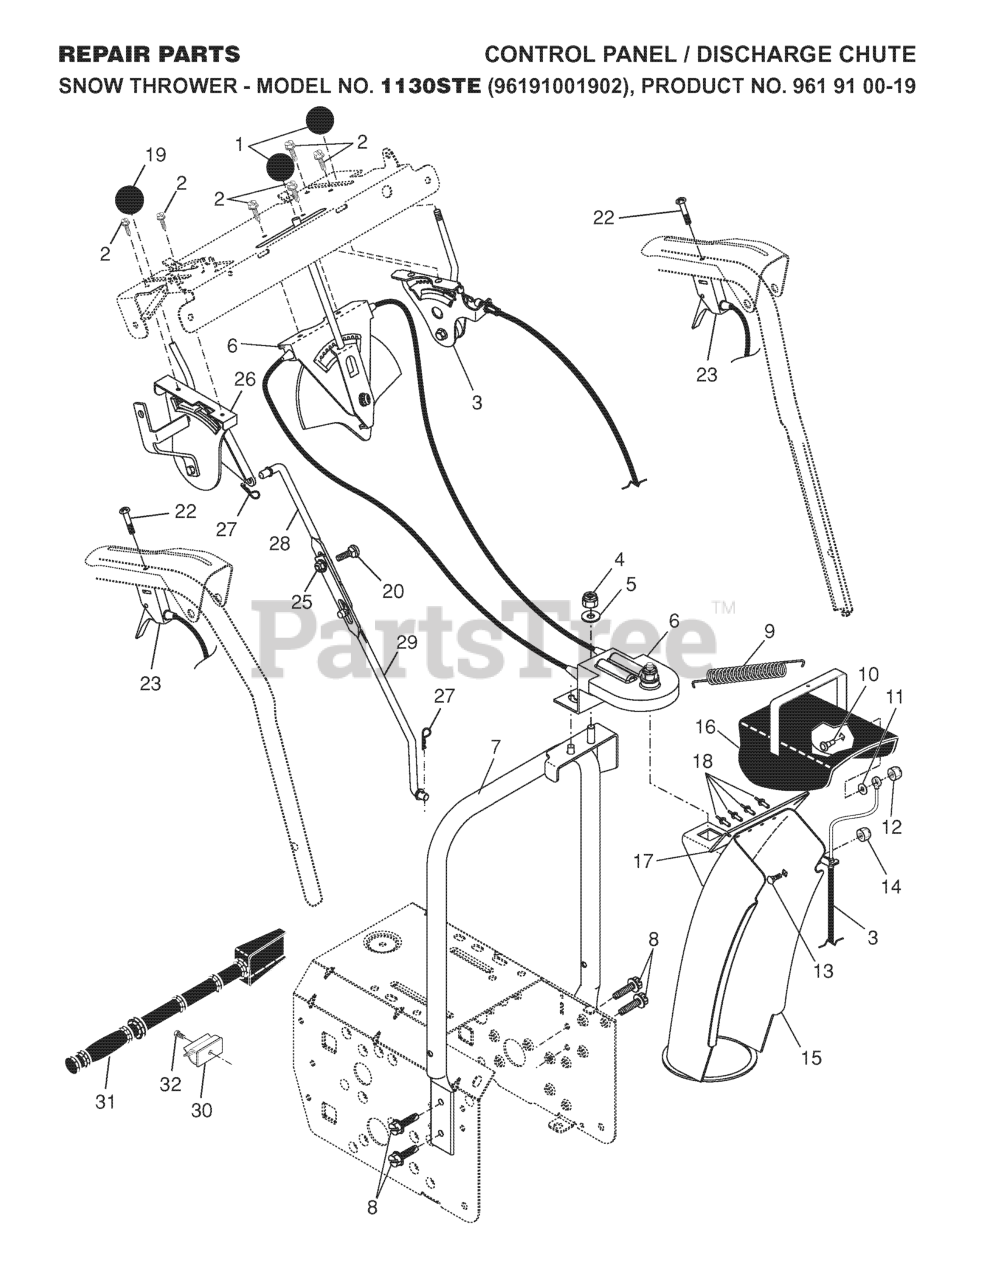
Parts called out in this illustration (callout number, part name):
1	KNOB LEVER, BLACK
2	SCREW #10-24 X 5/8
3	CONTROL.CABLE.DEFLECTOR
4	NUT
5	WASHER
6	CONTROL ASSEMBLY,CHUTE ROTATER
7	SUPPORT, PIVOT
8	SELF-TAPPING SCREW 5/16-18X3/4
9	SPRING.DEFLECTOR.REM.CHUTE
10	BOLT, SHOULDER
11	WASHER, NYLON FRICTION
12	NUT.HEX.FLANGE.1/4
13	BOLT
14	NUT.LOCK.5/16-18
15	CHUTE ASSEMBLY
16	DEFLECTOR.WELDMENT.PNT.ORANGE
17	SEAL, DEFLECTOR
18	RIVET BLIND
19	RED KNOB SHIFTER
20	BOLT
23	STEERING.CONTROL.SNOW.BLUE
25	NUT.FLANGE.5/16
26	HEAD ASSY SPEED
27	SPRING RETAINER
28	ROD, UPPER SPEED CONTROL
29	ROD, LOWER SPEED CONTROL.SNOW
30	CLIP.CLEANOUT.TOOL
31	CLEAN OUT TOOL
32	SCREW.HWH.13-16-5.8.BZP
